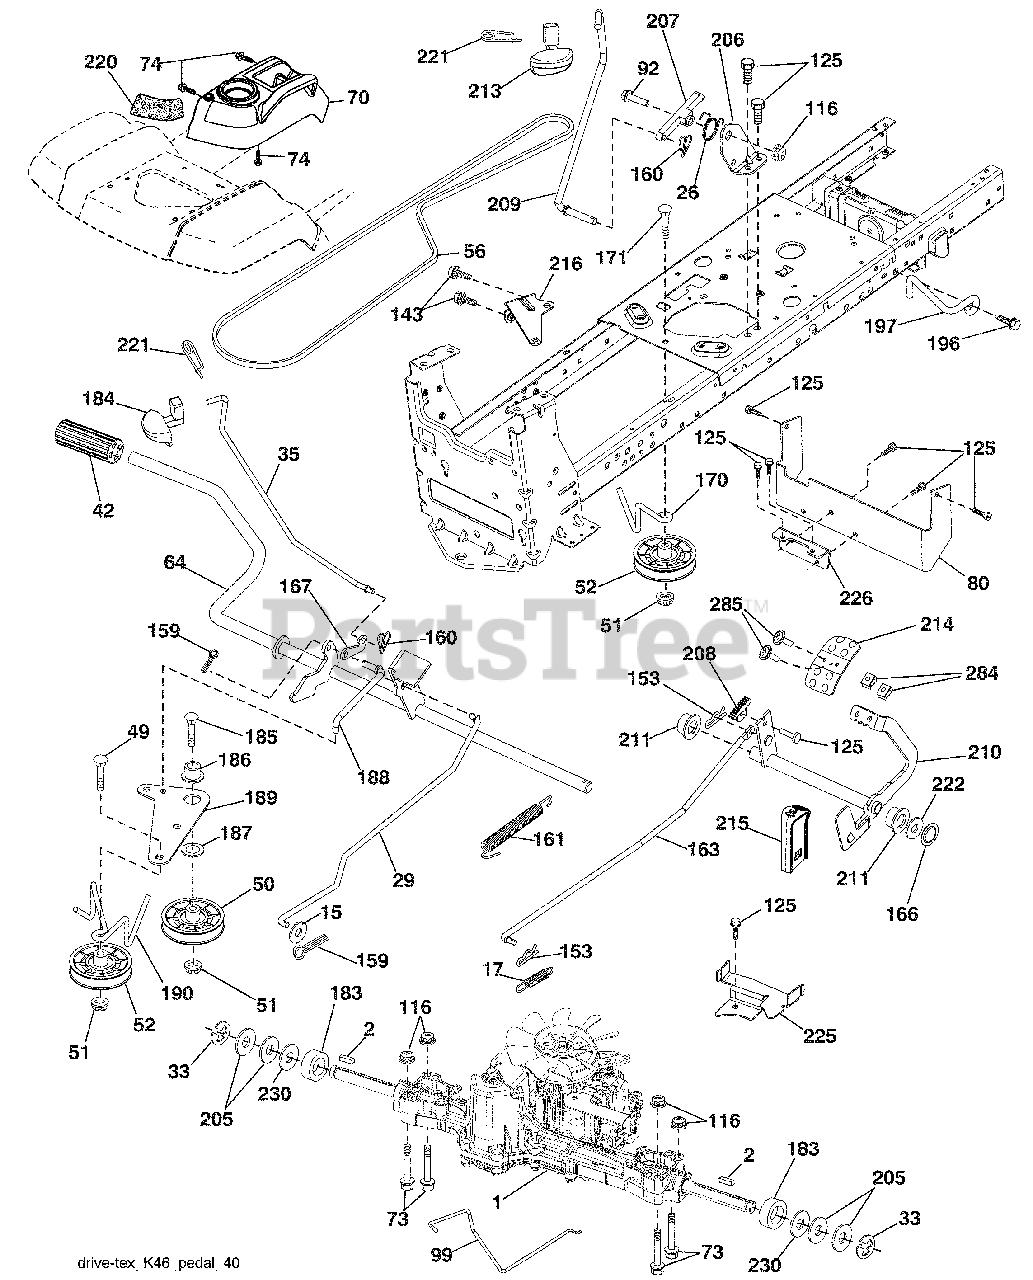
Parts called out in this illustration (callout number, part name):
1	Transaxle, TUFFTORQ K46CR.PDL
15	Washer 13/32 x 13/16 x 16 Ga.
17	Spring, Brake
26	Spring Return Cruise
29	Rod, Brake
35	Rod, Brake, Park
42	Cover, Foot Pedal
50	Pulley Idler Flat
51	Lock Nut 3/8-16
52	Idler V-Groove 910" Offset
56	V-Belt, Drive
64	Shaft Asm. Pedal Brake Control
70	Console
73	Bolt Hex Flghd 5/16-18 Gr. 5
74	Screw
80	Bracket Strap Torque
92	Bolt Fin Hex 5/16-18 unc x 1.25
99	Rod Spring Bypass
116	Nut Lock Hex Flange 5/16-18
125	Screw 5/16-18 x 3/4
143	Screw 5/16-18 x 1/2
153	Retainer Spring
159	Pin Cotter 1/8 x 3/4
160	Retainer Clip
161	Spring, Return, Clutch
163	Rod Pedal Control
166	Nut Push
167	Latch Brake Parking
170	Keeper Belt Centerspan
171	Bolt RDHD SQNK 3/8-16 unc x 2
183	Spacer Split
184	Handle Parking Brake
185	Bolt Rdhd Sqnk 3/8-16 x 2-3/4 Gr. 5
186	Spacer Retainer
187	Washer
188	Link Clutch Ground Drive
189	Bellcrank Ground Drive
190	Keeper Bellcrank Ground Drive
196	Screw 3/8-16 x 1
197	Bracket Clutch Anti-Rotation
206	Bracket Mount Latch Cruise
207	Latch Control Cruise
208	Gear Sector Control Cruise
209	Rod Control Cruise
210	Rocker Asm. Pedal Control
211	Bearing Nylon
213	Knob Control Cruise
214	Pedal Forward
215	Pedal Reverse
216	Bracket Pulley Idler
220	Reflector RH
221	Retainer Spring Clip Handle
222	Washer 21/32 x 1-1/4 x 10 Ga.
225	Keeper Belt Trans.
226	Bracket Mount Touque
230	Washer Hardened
284	Nut U-CHNL 1/4-20 550DP .350 PNL
285	Screw PHD 1/4-20 Box Drive
